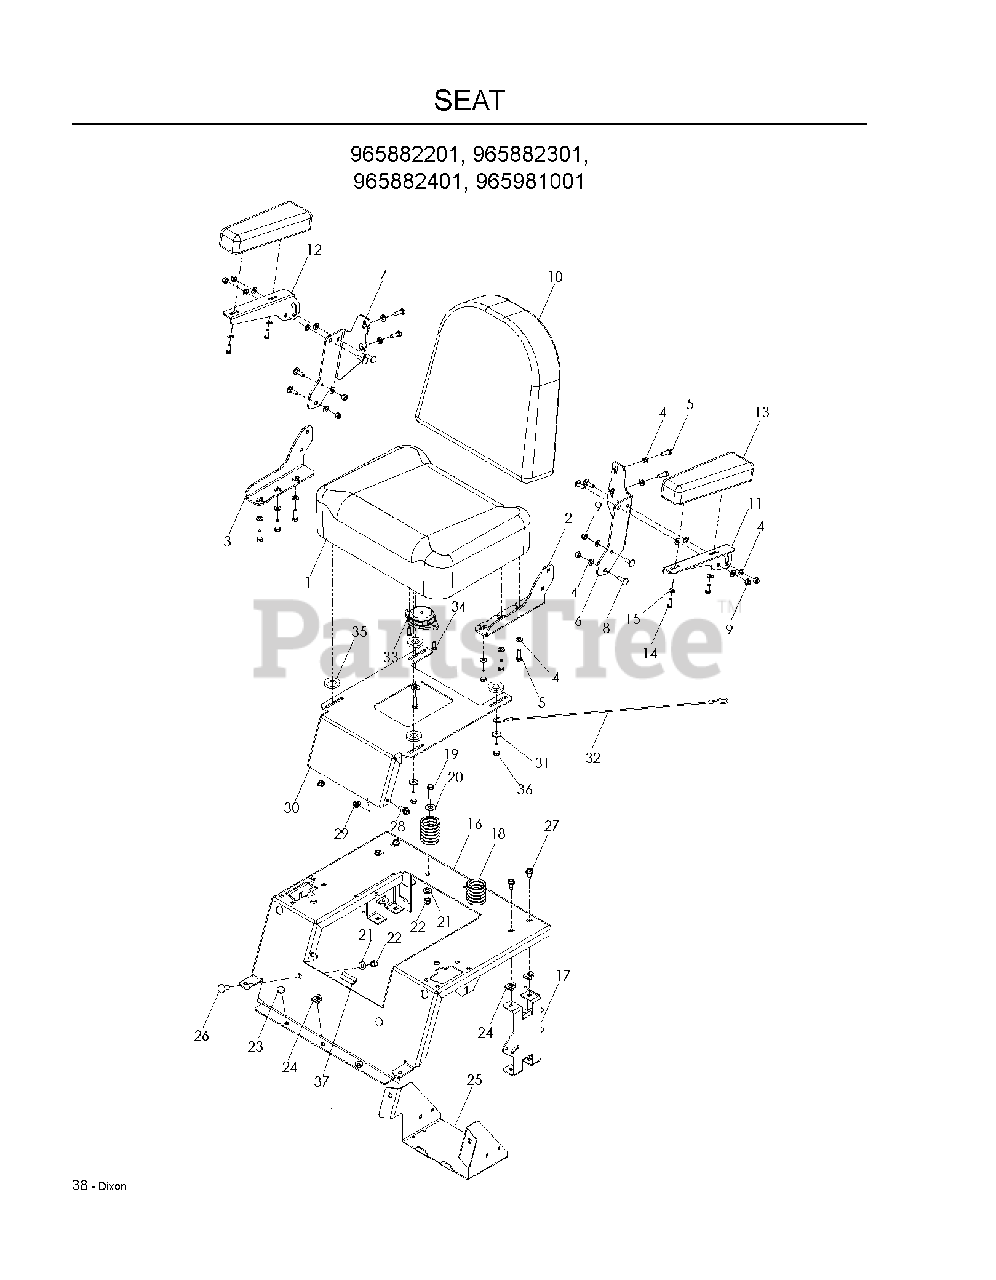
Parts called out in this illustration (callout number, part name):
1	CORDURA SEAT CUSHION
2	SEAT BOTTOM BRKT LH
3	SEAT BOTTOM BRKT RH
4	FLAT WASHER 5/16 SAE
5	5/16-18X1 HHB G5W/NY
6	SEAT BACK BRKT LH
7	SEAT BACK BRKT RH
8	RHSNB 5/16C X 1
9	NUT 5/16 NYLOC
10	SEAT BACK
11	ARM REST BRACKET LH
12	ARM REST BRACKET RH
13	ARMREST
14	HCS 1/4C X 3/4 HCS
15	WASHER 1/4 SAE
16	SUPPORT, SEAT MED FLAT, BLUE
17	SUPPORT, REAR SEAT, BLACK
18	SPRING, SEAT
19	HCS 3/8C X 1 1/4 GR5
20	WASHER 3/8 FLAT
21	WASHER 3/8 SAE FLAT
22	NUT 3/8-16 NYLOC
23	GROMMET, BUMPER
24	U-CLIP 5/16-18 NUT RETAINER
25	BOX, BATTERY, BLACK
26	RHSNB 3/8C X 1
27	BOLT 5/16-18 X 3/4
28	SB 5/16-18 HEX HD GD5, BLK ZN
29	5/16-18 NYLOC FLANGE NUT
30	PAN, SEAT, BLUE
31	WASHER 5/16 FLAT
32	SEAT LANYARD
33	SEAT SWITCH MILSCO
34	SCR 1/4-20X3/4 SLTD RDHD GR2ZD
35	WASHER NYLON
36	HCS 5/16C X 1
37	CLIP-1.06
